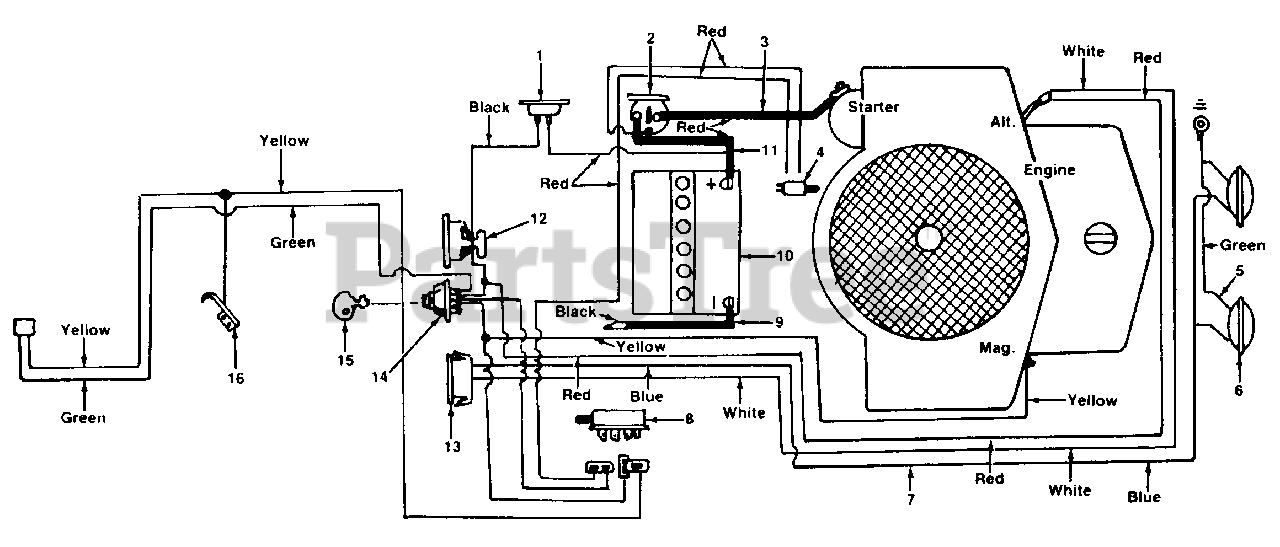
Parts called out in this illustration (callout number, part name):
1	Circuit Breaker
2	Solenoid
3	Wire
4	Safety Switch
5	Ground Wire
6	Head Light
7	Wire Harness
8	Safety Switch
9	6 Ga. Black Wire
10	Battery 12V
11	Wire
12	Ammeter
13	Light Switch
14	Ignition Switch
15	Ignition Key
16	Spring Switch
